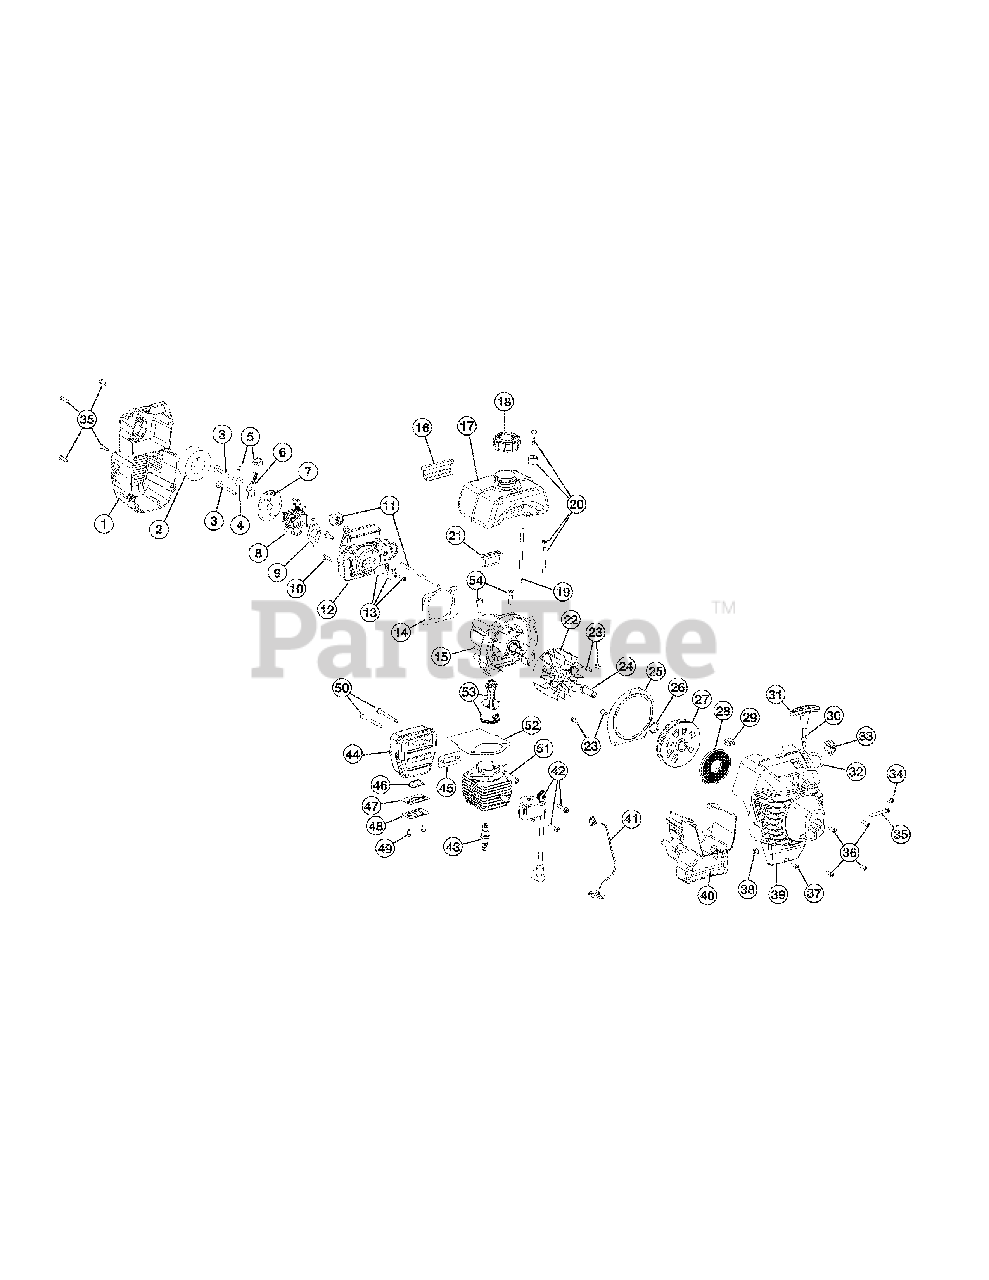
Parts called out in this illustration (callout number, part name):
1	Air Cleaner Cover Assembly (includes 2 & 34)
2	Air Cleaner Filter
3	Carburetor Mounting Screws
4	Wavey Washer
5	Choke Knob & Screw
6	Choke Lever Assembly (includes 5)
7	Choke Lever & Plate (includes 6)
8	Carburetor Assembly (includes 9 & 20)
9	Carburetor Gasket
10	Carb Mount Screw
11	Primer and Hose Assembly
12	Carburetor Mount Assembly (includes 10, 13 & 14)
13	Reed Assembly
14	Carburetor Mount Gasket
15	Crankcase Service Assembly (includes 10 & 23)
16	Rear Mounting Pad
17	Fuel Tank Assembly (includes 18 & 20)
18	Fuel Cap Assembly
19	Fuel Return Line
20	Fuel Line Assembly
21	Front Mounting Pad
22	Flywheel Assembly
23	Screw
24	Square Nut Drive
25	Pulley Retainer Assembly
26	Palnut
27	Recoil Pulley Assembly
28	Recoil Spring
29	Eyelet Retainer
30	Pull Handle
31	Rope Guide
33	Switch Assembly (includes 41)
34	Anti-Rotation Screw
35	Clamping Screw
36	Housing Screw
37	Cover Screw
38	Clamping Nut
39	Starter Housing Assembly (includes 23, 25-38)
40	Shroud Extension and Stand
41	Wire Lead
42	Module Assembly
43	Spark Plug
44	Muffler Assembly (includes 45-50)
45	Exhaust Gasket
46	Spark Arrestor
47	Exhaust Hood Diverter
48	Exhaust Hood
49	Screw
50	Muffler Mounting Bolt Assembly
51	Cylinder Assembly (includes 52 & 53)
52	Piston & Rod Assembly
53	Cylinder Gasket
54	Cylinder Bolt
